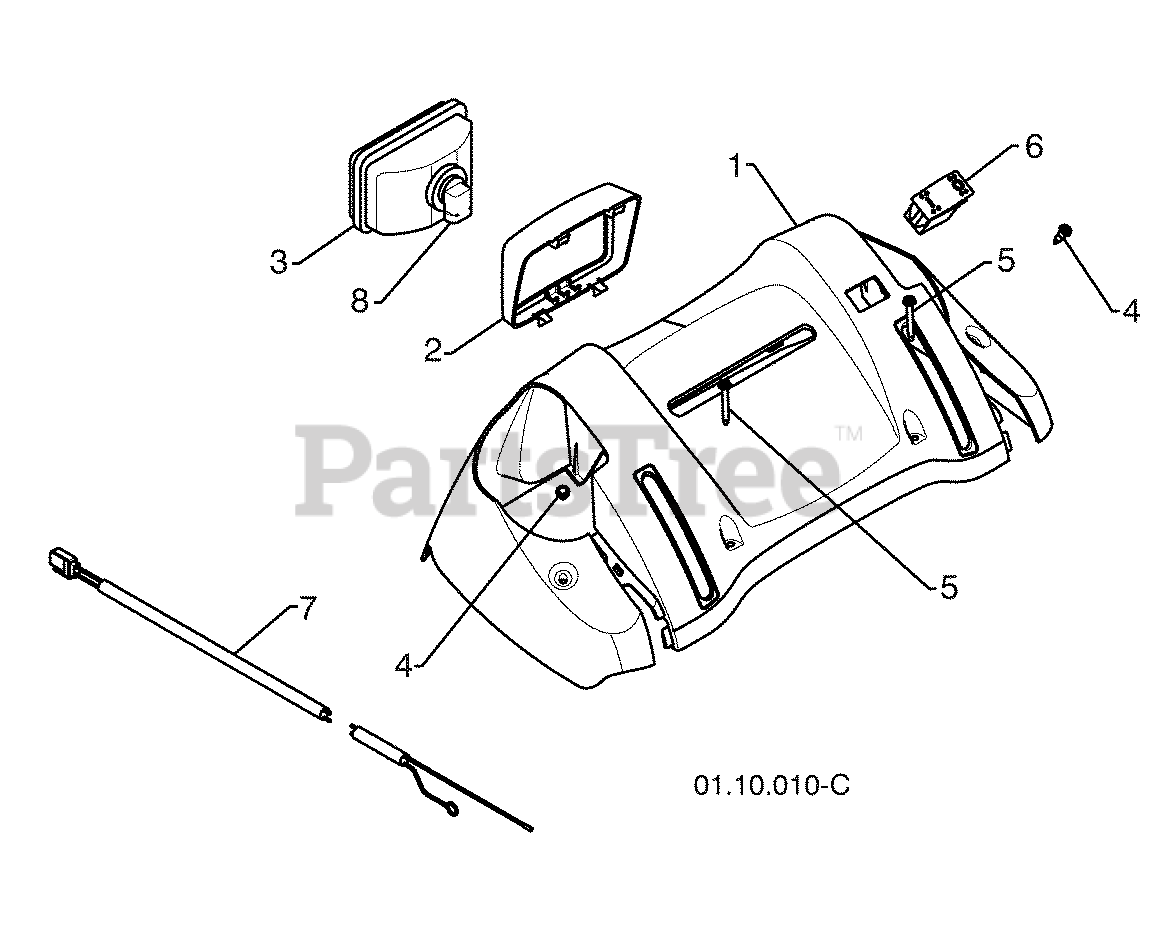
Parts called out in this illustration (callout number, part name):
1	CONSOLE PANEL GRAY
2	HEADLIGHT BEZEL GRAY
3	HALOGEN HEADLIGHT
4	SHOULDER SCREW 10-24 X .625
5	SCREW 10-24 X 1.25
6	GRIP SWITCH
7	WIRE HARNESS
